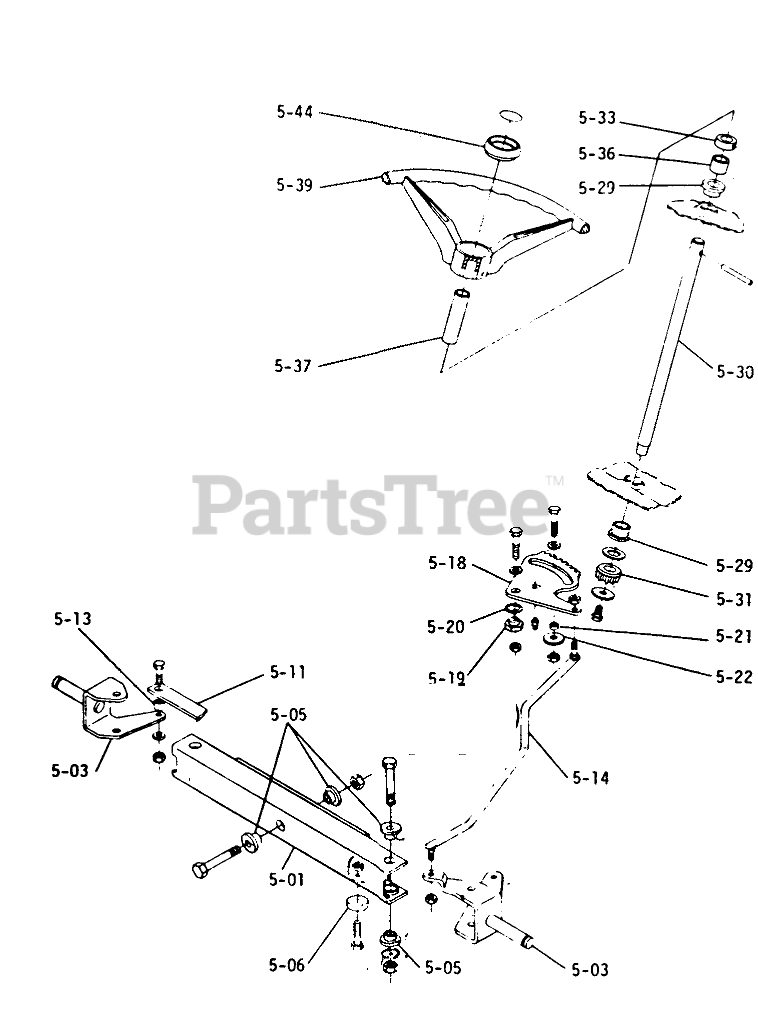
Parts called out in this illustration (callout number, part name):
5-01	ASSY FRT AXLE
5-03	Spindle R.H.
5-04	Bolt-Shoulder
5-05	BUSHING
5-06	Washer Axle Stop
5-11	Tie Rod
5-13	SPACER
5-14	STEERING ROD R
5-18	Sector-Steering
5-19	STEERING ARM
5-20	WASHER-BOWED
5-21	SPACER
5-22	Washer
5-29	BEARING
5-30	SHAFT STEERING
5-31	GEAR-STEERING PINION
5-33	Collar
5-36	Spacer
5-37	Sleeve
5-39	STEERING WH 13" SOFT
5-44	Cap-Steering Wheel
5-44	STEERING WHEEL INSE
